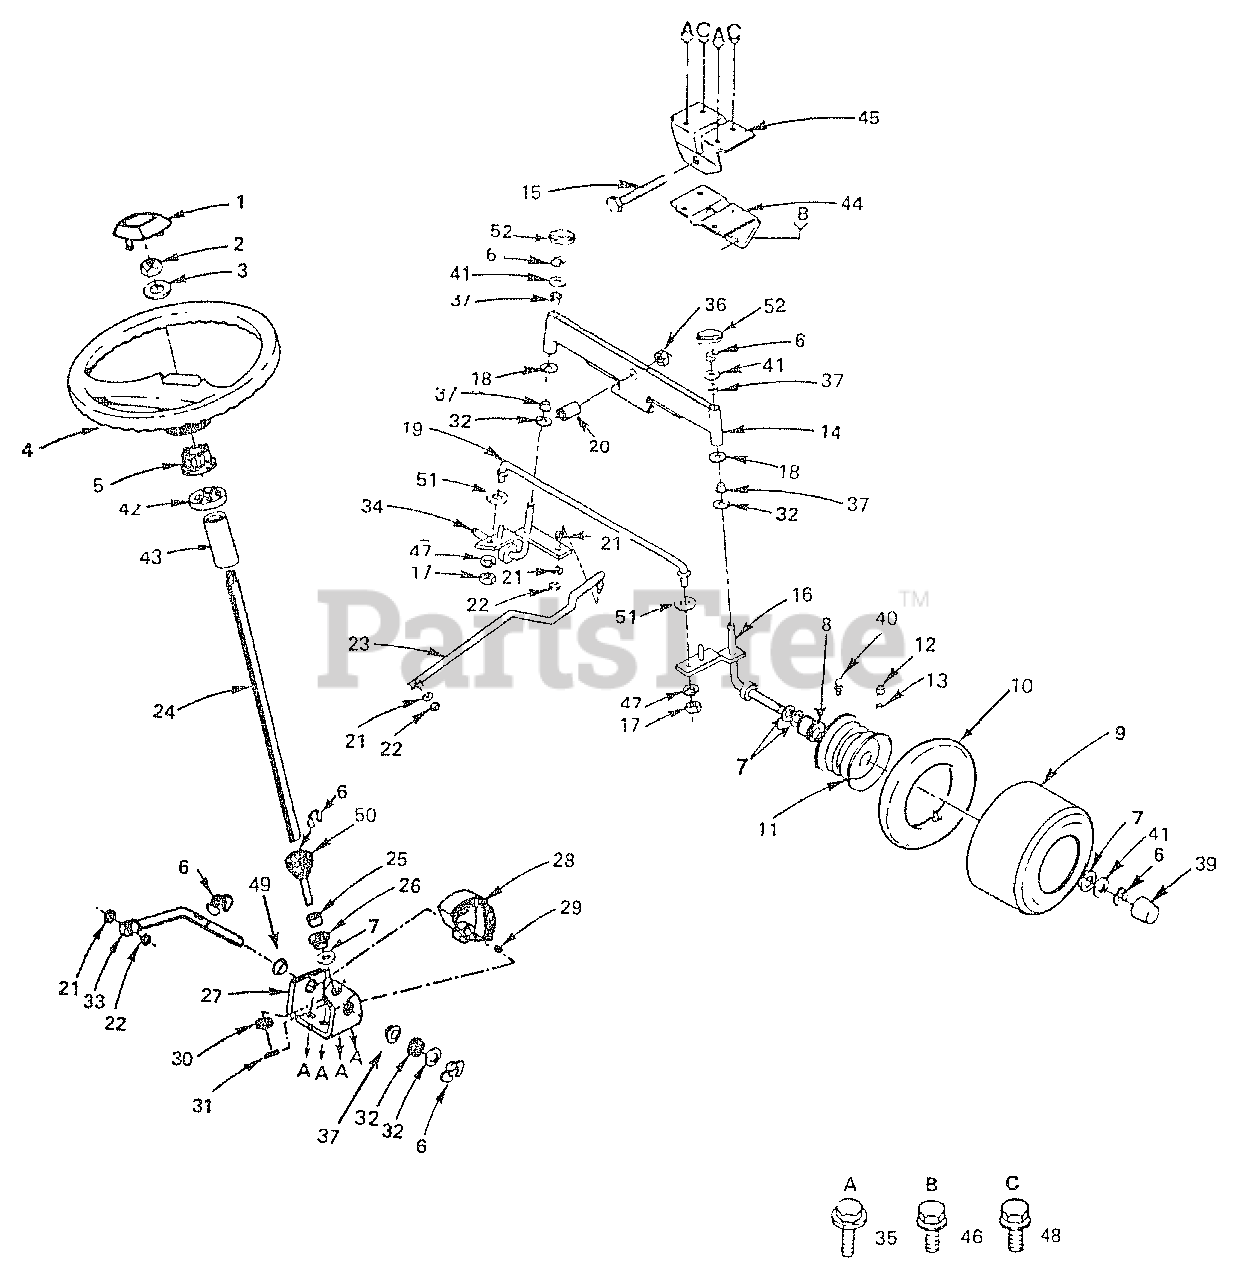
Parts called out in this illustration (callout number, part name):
1	Insert - Steering Wheel
2	Nut - Hex Toplock Jam 1/2-20
3	Washer 17/32 x 2-1/4 x .160
4	Steering Wheel - 13"
5	Adapter - Wheel, Steering
7	Washer - 25/32 x 1 1/4 x 16 Ga.
8	Bearings - Wheel, Front
9	Tire - Rib Tread 15 x 6.00-6 (Tubeless)
10	Tube - Tire
11	Rim Assembly - 6 Front
12	Stem - Valve
13	Cap - Valve
14	Axle Assembly - Front
15	Bolt -Hex 5/8-11 x 3-3/4
16	Spindle Assembly. - R.H.
17	Nut- Hex 5/16-24
18	Washer - 27/32 X 1-1/4 X 16 Ga.
19	Tie Rod
20	Bearing
21	Lockwasher - 3/8
22	Nut - Hex 3/8-24
24	Shaft Assembly - Steering
26	Bushing - Steering Rod
27	Bracket Assembly - Steering
28	Gear-Sector
29	Woodruff Key - 3/16 x 3/4
30	Washer-Hardened
31	Drive Pin - 3/16 X 1
32	Bearing - Thrust
33	Rod - Steering
34	Spindle Assembly - L.H.
35	Screw - Hex Washer Hd. - Thread Forming - Type TT - 3/8 -16 x 3/4
36	Nut- Lock Flange, 5/8-11
39	Cover- Wheel, 6", Front
40	Grease Fitting
41	Washer 25/32 x 1-5/8 x 16 Ga.
42	Spacer - Shaft, Steering
43	Tube - Shaft, Steering
44	Support - Saddle, Front
45	Support - Saddle, Rear
46	Screw - Hex Washer Thd. Rolling - 5/16-18 X 1/2
47	Lockwasher - 5/16
48	Screw - Hex Washer Hd. Thread Forming - Type TT - 3/8-16 x 1
49	Nyliner - Snap In
50	Gear- Pinion
51	Washer -11/32 X 3/4 X 16 Ga.
52	Spindle Cap
